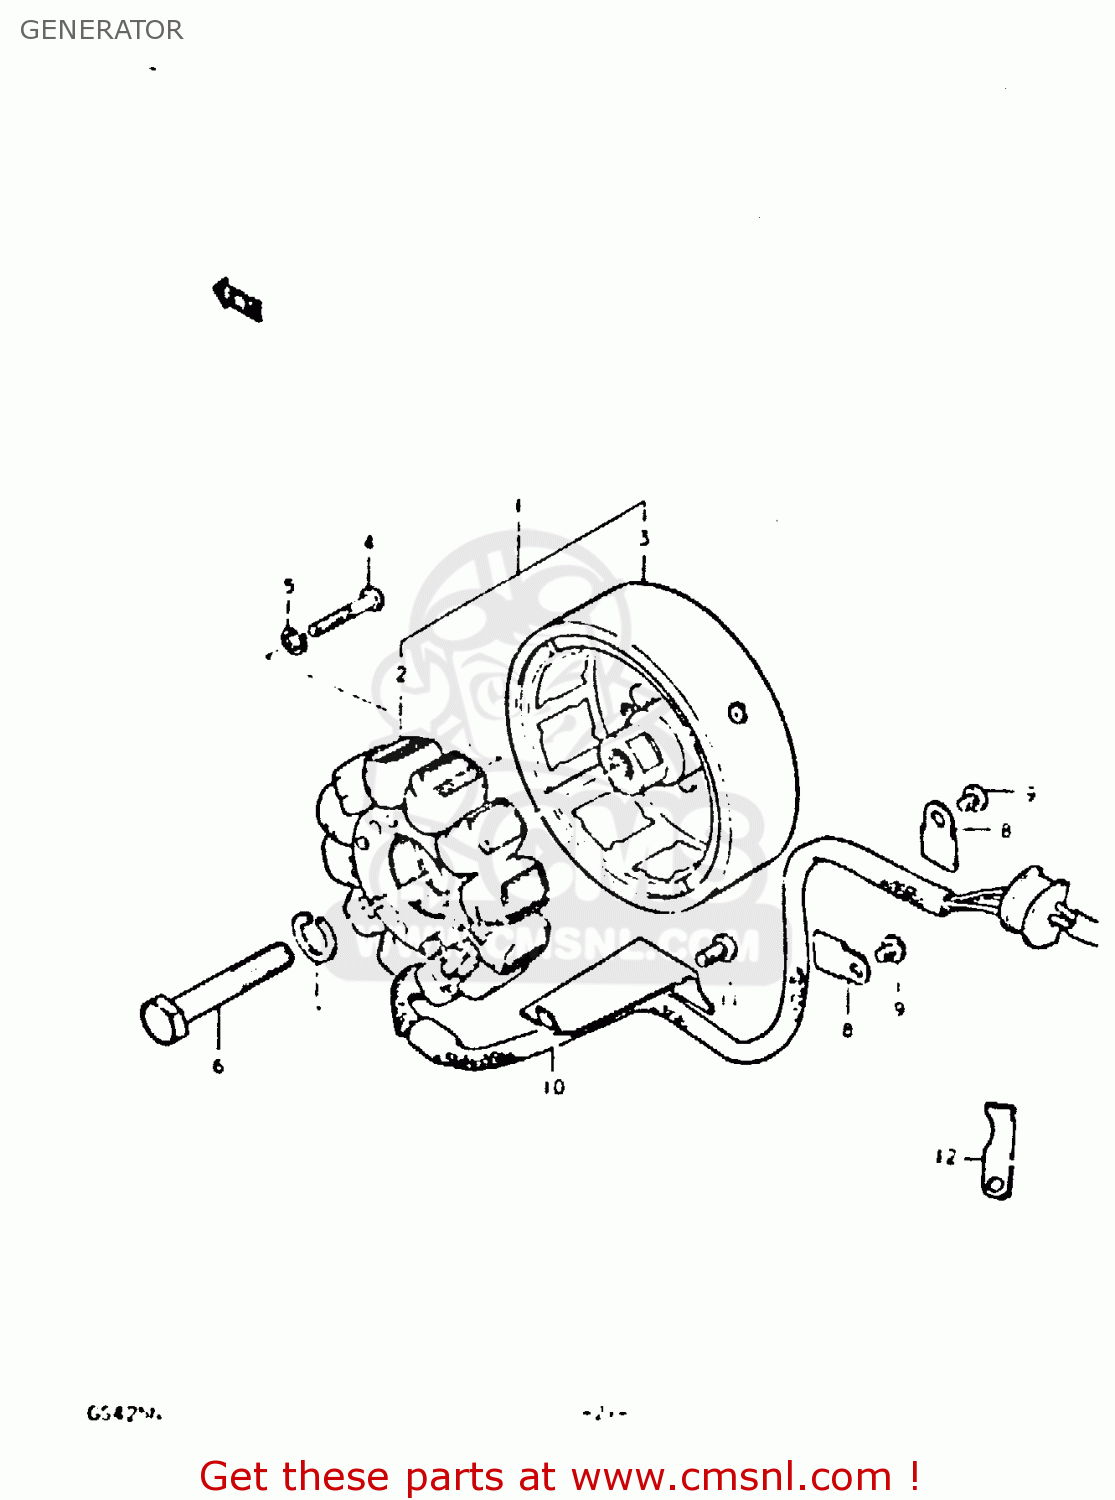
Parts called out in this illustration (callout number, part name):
1	GENERATOR ASSEMBLY
2	STATOR ASSEMBLY
3	ROTOR ASSEMBLY
4	SCREW
5	LOCK WASHER
6	BOLT 12X45
7	WASHER,LOCK 12
8	CLAMP,GENERATOR LEAD WIRE
9	SCREW
10	CLAMP,GENERATOR LEAD WIRE
11	SCREW
12	CLAMP,GENERATOR LEAD WIRE
